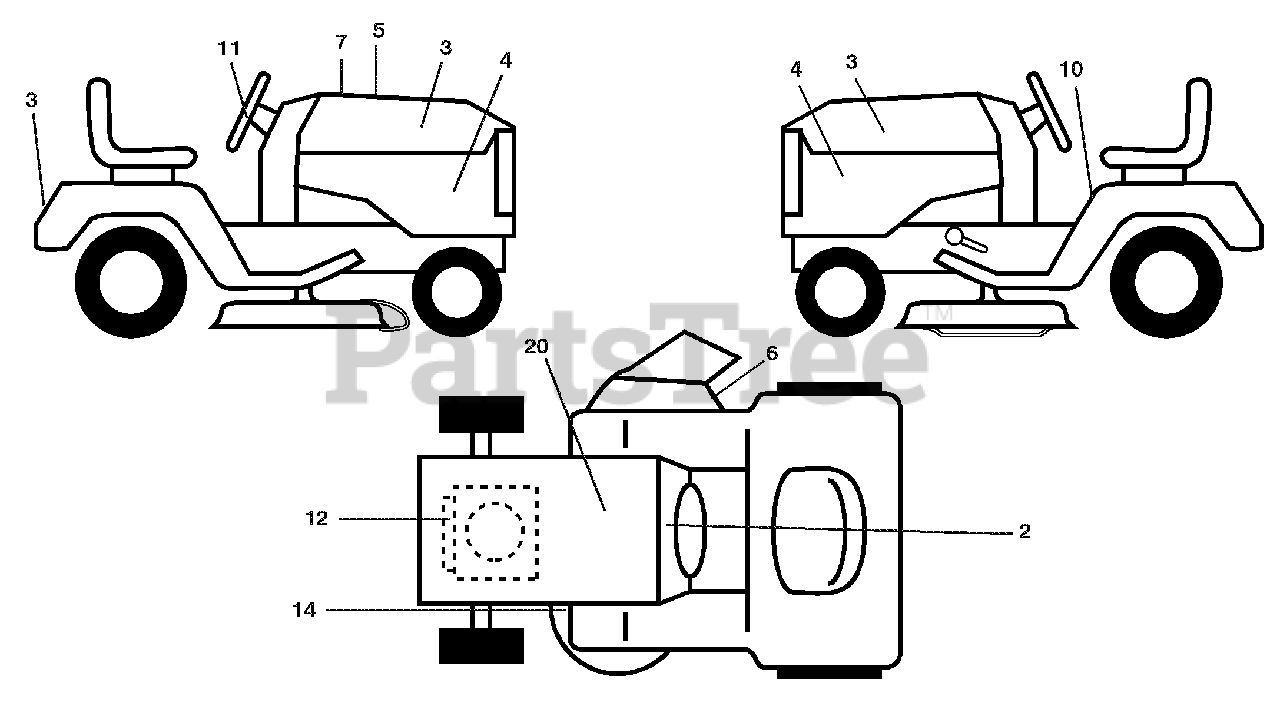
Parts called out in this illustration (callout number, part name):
2	Decal Dash
3	Decal Hood
4	Decal Side Panel Logo
5	Decal Hood Cust Resp.
6	Decal Warning, Keep Hand Away
7	Decal Replacement Parts
10	Decal Fender Danger E/F
11	Decal Ins Strg Whl
12	Decal Engine
14	Decal V-Belt Schematic
20	Decal Bat Dan/Psn
20	Decal By Pass Lt Hydro
20	Decal Handle Lift
20	Pad Footrest LH
20	Pad Footrest RH
20	Manual, Owner's
